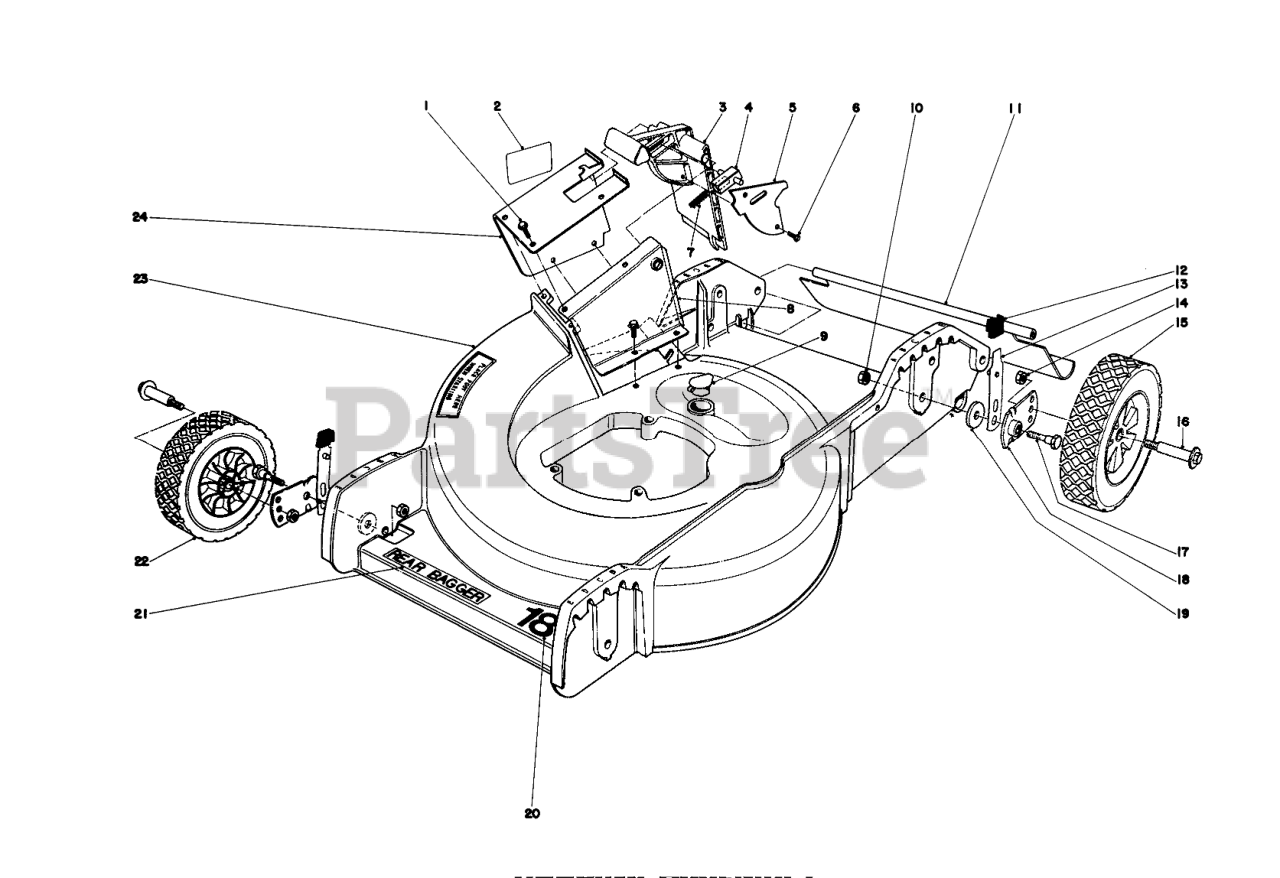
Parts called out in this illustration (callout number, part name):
1	SCREW
2	Decal Door
3	Door Mulching
4	Door Latch
5	Cover Door
7	SPRING-COMPRESSION, LATCH
8	Inner Tunnel
9	WASHOUT PLUG
10	Nut
11	SHIELD - TRAILING
12	KNOB-ARM
13	SPRING ARM ASM
14	Nut
15	WHEEL TIRE ASM 8 IN
16	BOLT-WHEEL
17	PIVOT SCREW
18	PIVOT ARM ASSY
19	PIVOT WASHER
20	Decal
21	DECK DECAL
22	WHEEL TIRE ASM 7 IN
23	Housing
24	Tunnel Outer
